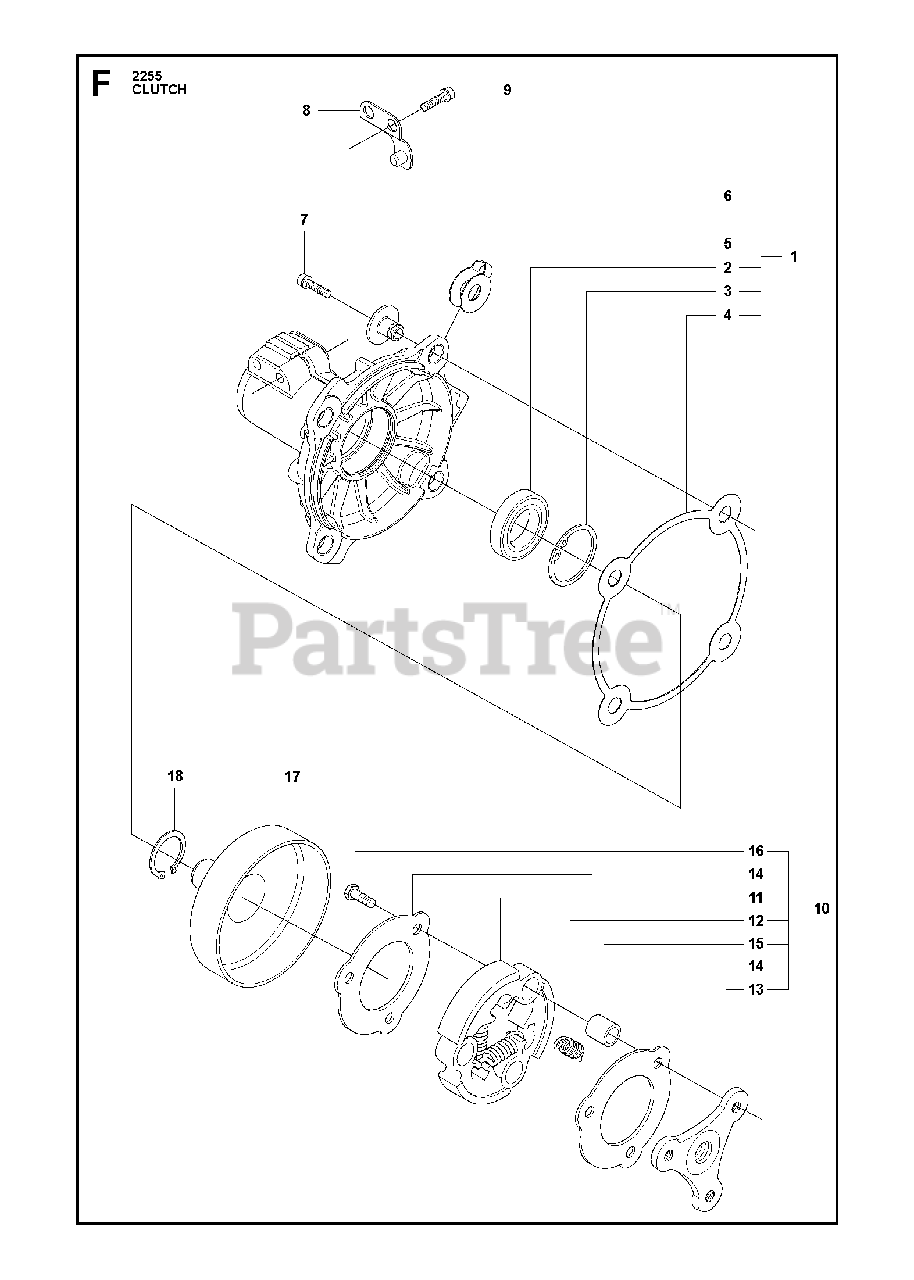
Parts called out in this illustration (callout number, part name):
1	CLUTCH COVER ASSY
2	BALL BEARING 6202-2RS1
3	RETAINING RING SGH 35
4	WASHER
5	SPRING PLATE
6	SPACING SLEEVE
8	LOCKING PLATE
10	RP CLUTCH ASSY
11	CLUTCH SHOE
12	CLUTCH SPRING
13	CLUTCH HUB
14	WASHER
15	BUSHING
16	SCREW
17	CLUTCH DRUM ASSY
18	RETAINING RING SGA 15
